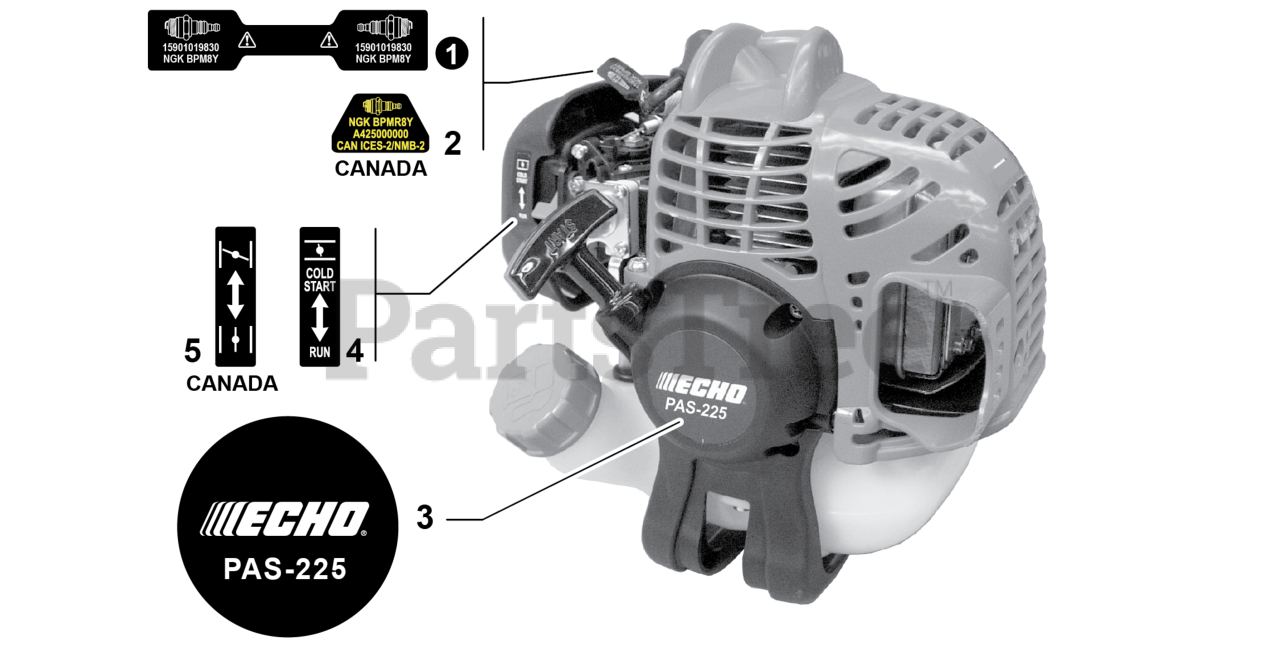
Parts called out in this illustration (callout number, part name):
1	LABEL - SPARK PLUG - BPM8Y
2	LABEL - SPARK PLUG - BPMR8Y
3	LABEL - MODEL PAS-225
4	LABEL - CHOKE
5	LABEL - CHOKE
